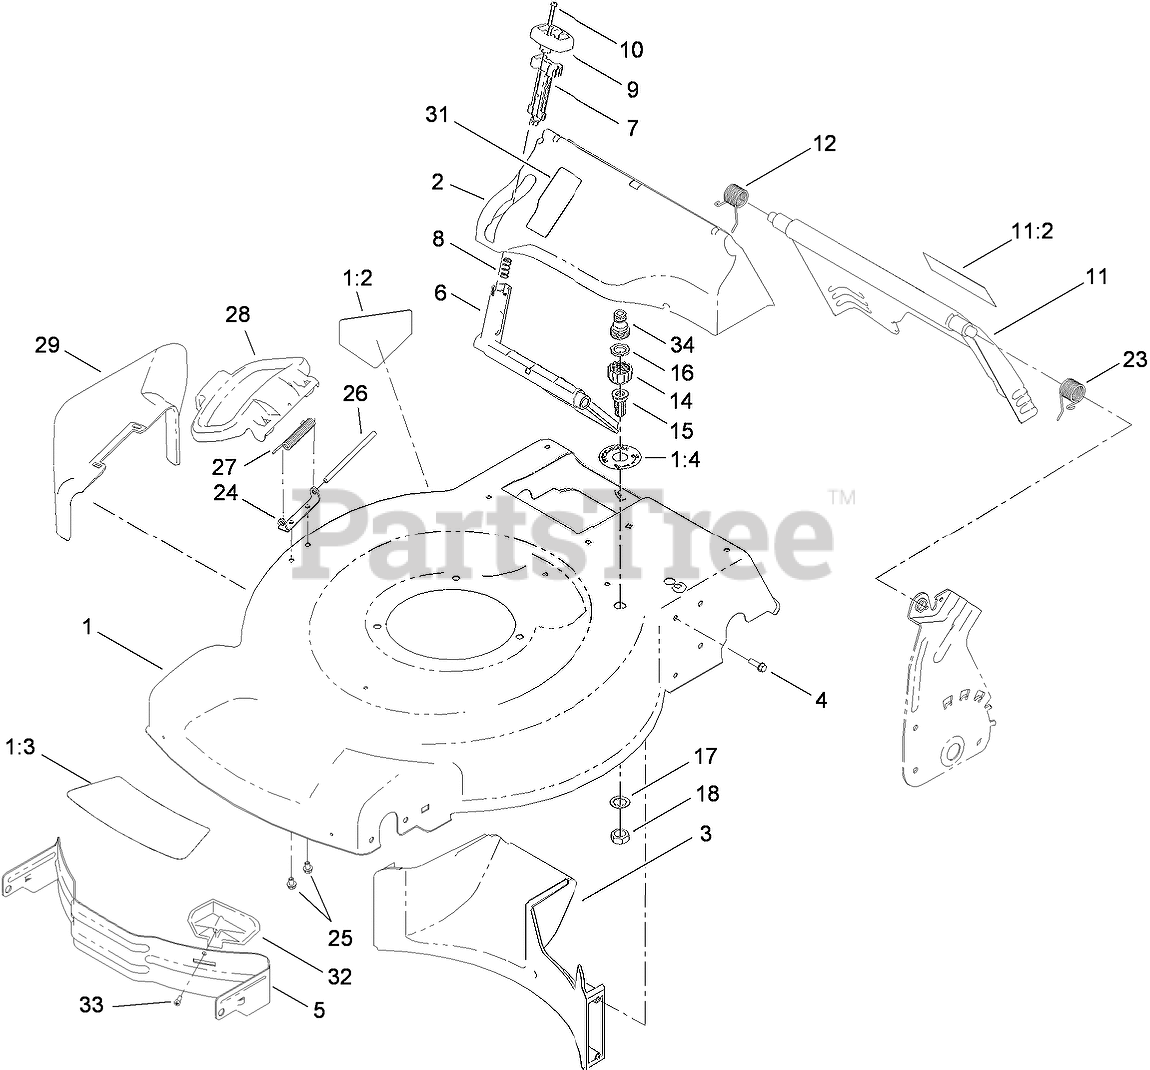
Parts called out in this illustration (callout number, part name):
1	HOUSING ASM
1:2	DECAL-DANGER
1:3	DECAL-RECYCLER
1:4	DECAL-PORT, WASHOUT
2	CHUTE-RECYCLE
3	BAFFLE-REAR
4	SCREW-HWH
5	BAFFLE-FRONT
6	DEFLECTOR-RECYCLE
7	LATCH-RECYCLE
8	SPRING-COMPRESSION
9	KNOB-RECYCLE
10	SCREW-PPH
11	REAR DOOR ASM
11:2	DECAL-WARNING
12	SPRING-TORSION
14	COUPLING-HOSE, WASHOUT PORT
15	PORT-WASHOUT
16	WASHER-SEAL, WASHOUT PORT
17	WASHER-TOOTH, INTERNAL
18	NUT-JAM
23	SPRING-TORSION
24	BRACKET-COVER
25	SCREW-HWH
26	ROD-COVER
27	SPRING-TORSION
28	DEFLECTOR-SIDE
29	CHUTE-DISCHARGE, SIDE
31	DECAL-BAG ON DEMAND
32	KICKER-FRONT
33	SCREW-PPH
34	ADAPTER-CONNECT, QUICK
